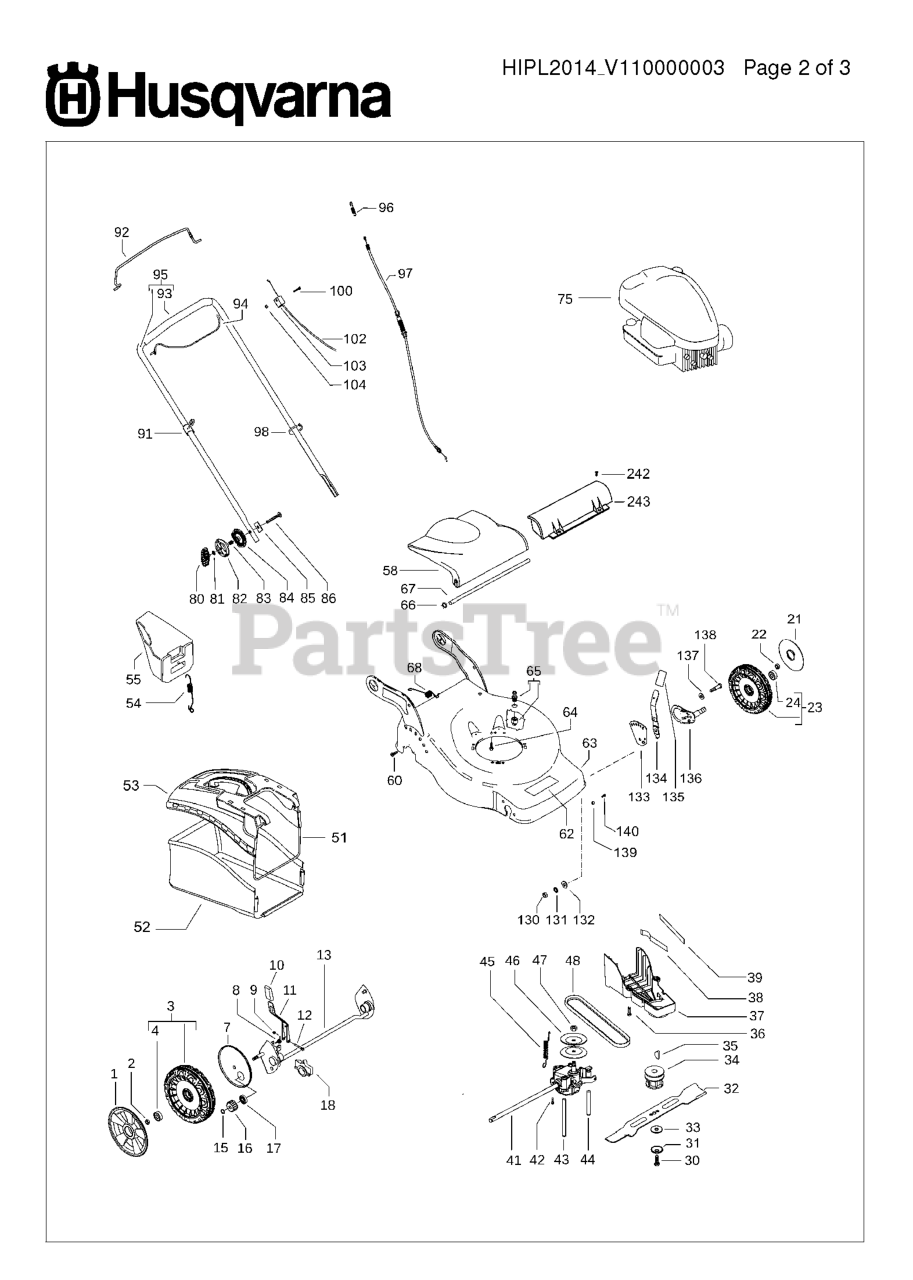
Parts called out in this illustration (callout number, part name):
32	MOWER BLADE COMBI
34	BLADE SUPPORT
102	BRAKE WIRE
